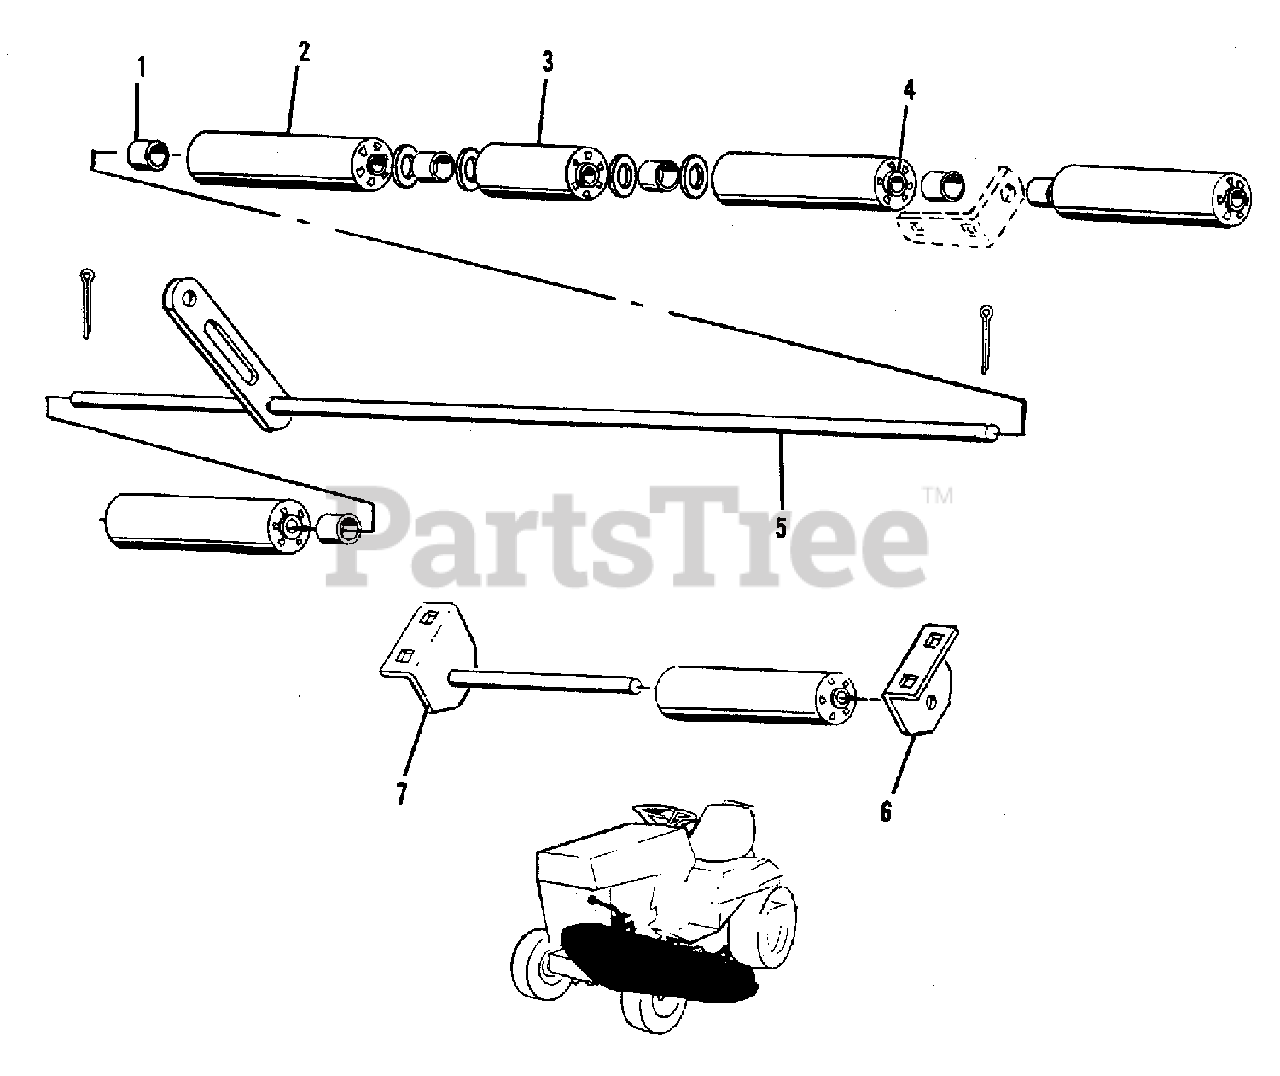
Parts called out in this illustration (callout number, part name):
1	SPACER, .66 ID
1	WASHER, .641 x 1-1/4 x 16 Ga.
2	ROLLER ASSEMBLY, Long (Includes BUSHING - Order As Required)
3	ROLLER ASSEMBLY, Short (Includes BUSHING - Order As Required)
4	BUSHING, Roller
5	SHAFT ASSEMBLY, 48" Mower
5	SHAFT ASSEMBLY, 42" Mower
5	PIN, 3/26 x 1, Cotter
6	BRACKET, Center Roller
6	BOLT, Carriage, 5/16NC x 3/4
6	LOCKWASHER, 5/16
6	NUT, 5/16NC
7	SHAFT ASSEMBLY, Center Roller
7	BOLT, Carriage, 5/16NC x 3/4
7	LOCKWASHER, 5/16
7	NUT 5/16NC
